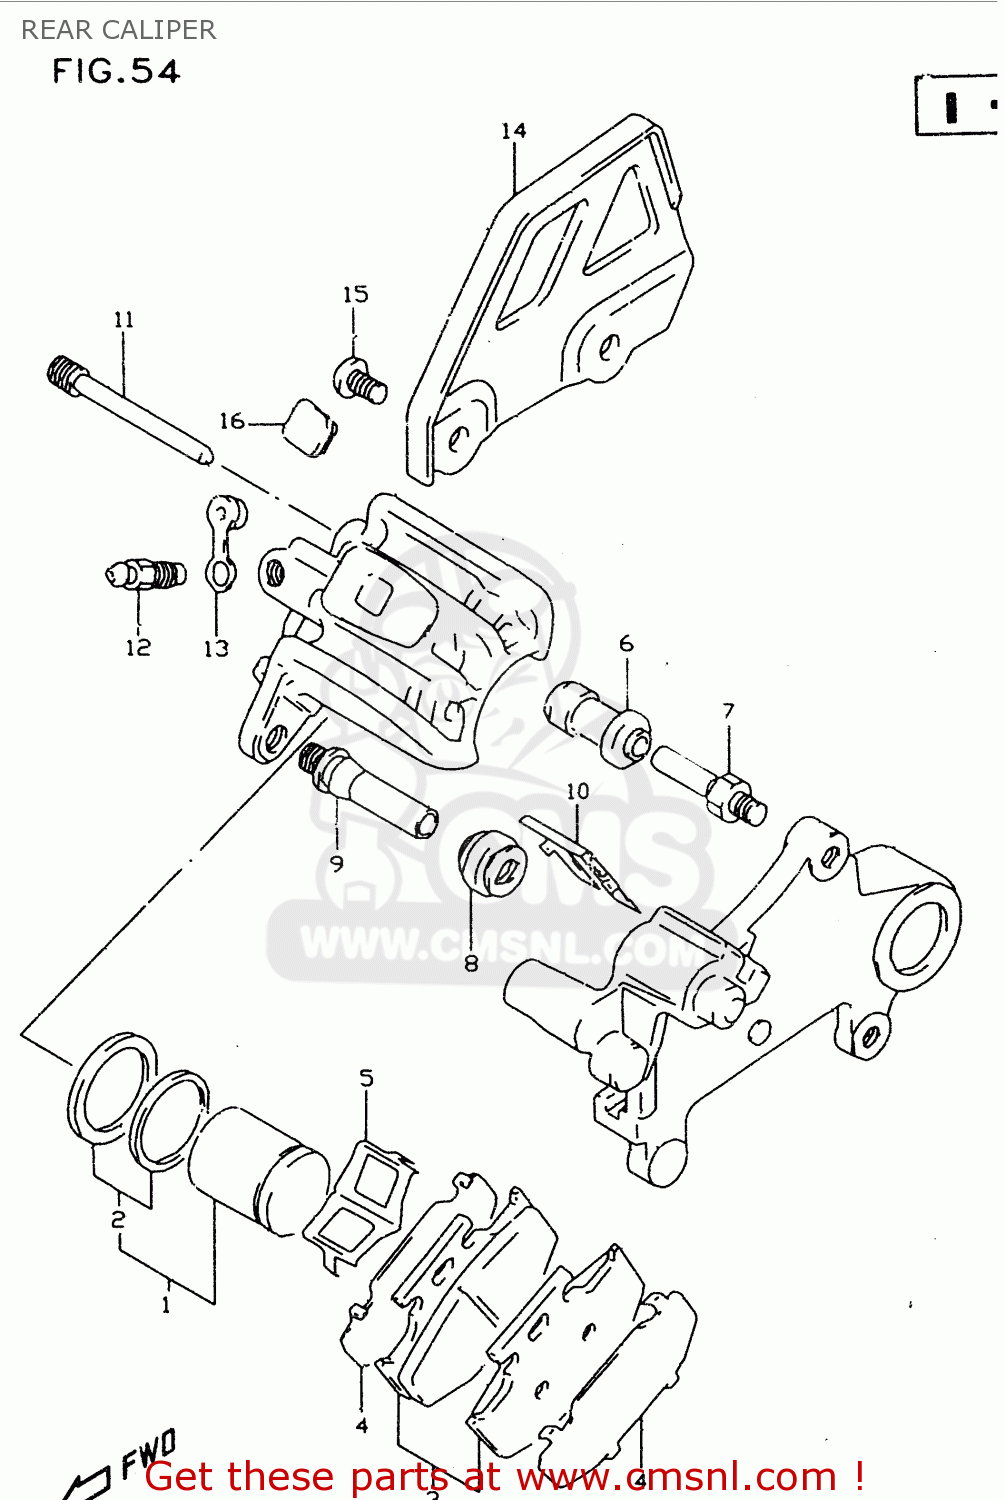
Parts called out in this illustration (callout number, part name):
1	PISTON SET
2	SEAL SET,PISTON
3	PAD SET (NAS)
4	SHIM
5	SPRING,PAD
6	BOOT
7	PIN,BOLT
8	BOOT
9	PIN
10	RETAINER,BRACKET
11	PIN,HANGER
12	BLEEDER
13	CAP,BLEEDER
14	GUARD,RR CALIPER
15	SCREW 6X12
16	COVER,RR CALIPER BODY
